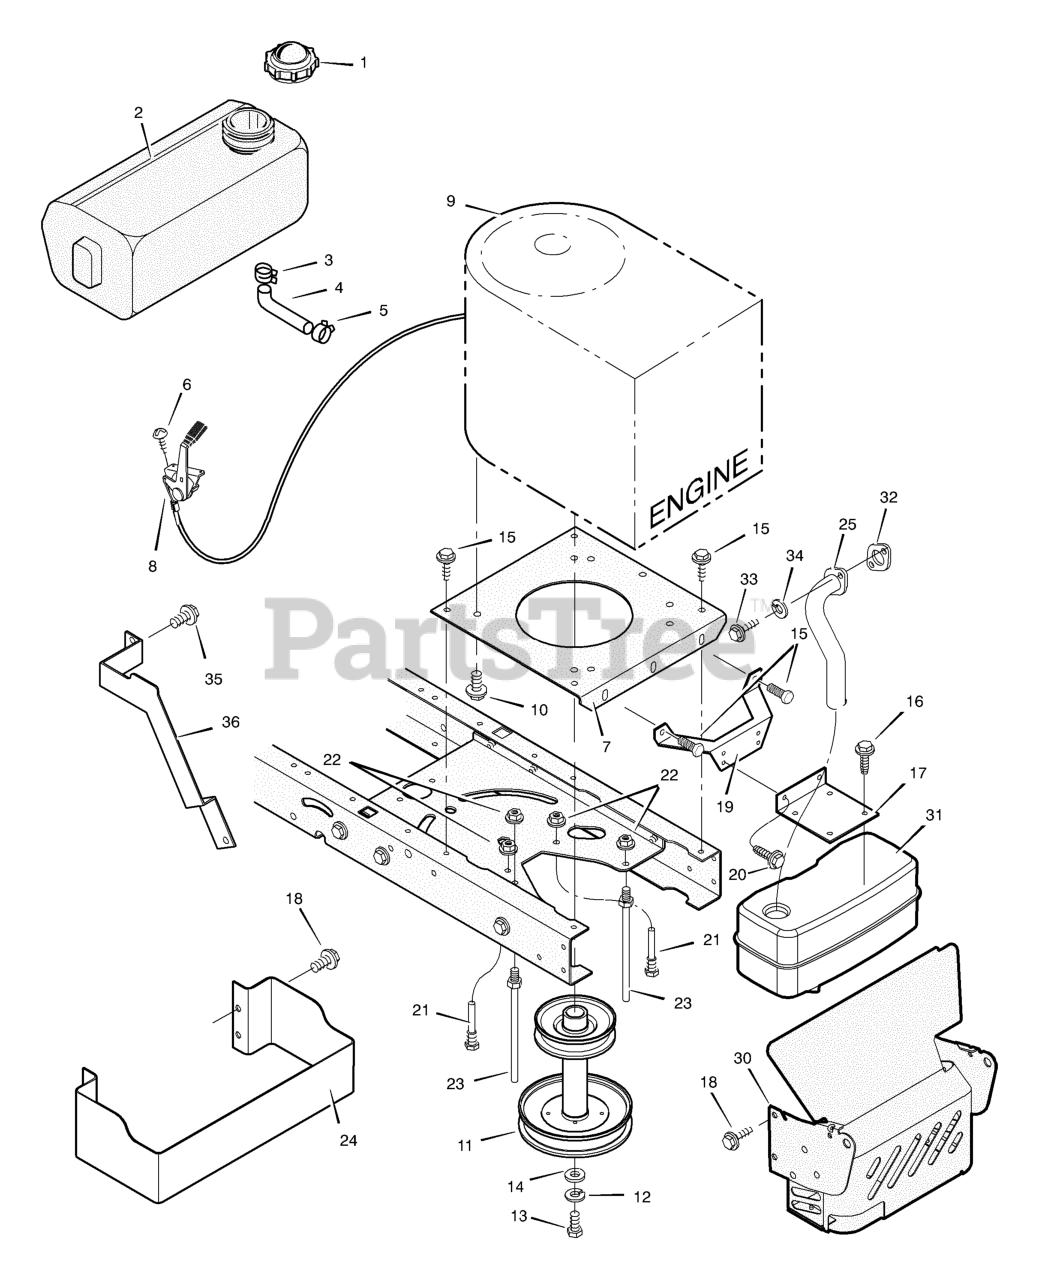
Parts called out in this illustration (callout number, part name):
1	Fuel Cap
2	TANK, Fuel 1.4 Gal.
3	Hose Clamp
4	Fuel Line (Must cut to length)
5	Hose Clamp
7	Plate, Engine
8	Throttle Control
9	Engine, Briggs & Stratton *
10	Bolt, Engine Mount
11	STACK PULLEY ASSEMBLY
12	Lockwasher
13	Bolt, Hex
17	Bracket, Muffler
19	Bracket, Muffler Mount
21	Guide, Belt
22	Nut, Flange
23	Guide, Belt
24	GUARD, Heat Shield
25	Exhaust Tube, Single
30	Shield, Heat
31	Muffler
32	GASKET, Exhaust
34	Washer
35	Bolt, Washer Hex Head
36	Guard, Exhaust Pipe
